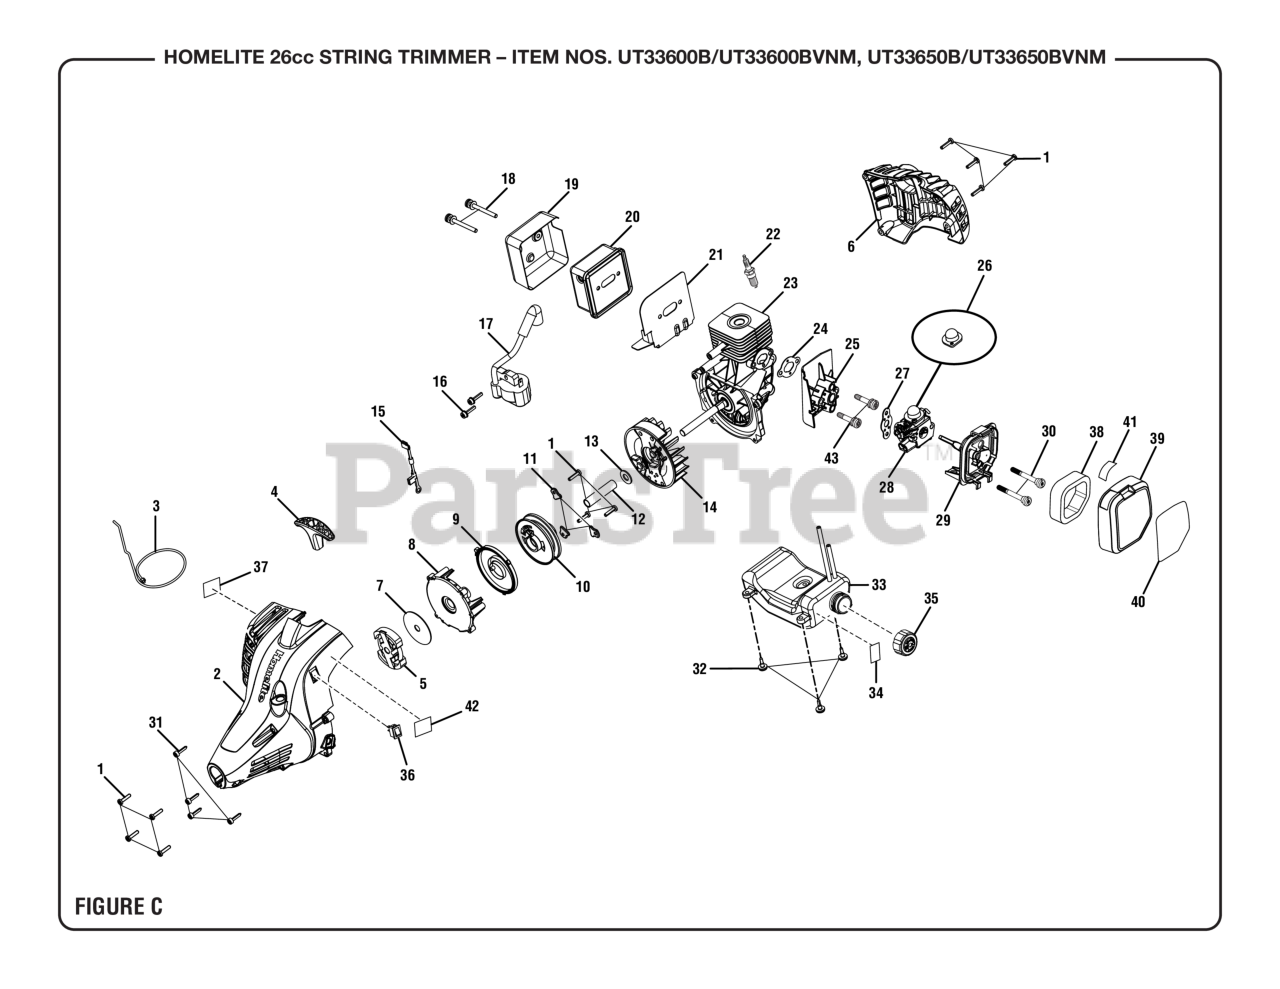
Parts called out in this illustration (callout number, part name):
1	Screw (M4 x 20 mm, T20 Torx Pan Hd. S.T.)
2	Starter Housing Assembly
3	Starter Rope (42 in.)
4	Pulley Handle
5	CLUTCH ASSEMBLY
6	Rear Housing
7	Washer (ID9.63 x OD50.75 x 1.10t)
8	Starter Housing
9	Spring & Container Assembly
10	Starter Pulley Assembly
11	Pulley Retainer
12	Spacer Tube
13	Washer (ID9.75 x OD20 x 1.6t)
14	Flywheel Assembly
15	Lead Assembly
16	Screw w/Washer (M4 x 19 mm, T20 Torx Pan Hd. S.T.)
17	Ignition Module
18	Screw w/Washers (10-24 x 2-1/8 in., T25 Torx Truss Hd.)
19	Muffler Housing
20	Muffler Assembly (Non "A" versions)
21	Muffler Gasket
22	SPARK PLUG CHAMPION - RCJ-6Y
23	Short Block Assembly
24	Inner Heat Dam Gasket
25	Heat Dam Deflector
28	Carburetor Assembly
29	Airbox Base Assembly
30	Screw (M5 x 45 mm, T20 Torx Truss Hd.)
31	Screw w/Washer (M4 x 16 mm, T25 Torx Truss Hd.)
32	Shoulder Screw w/Washer (M4 x 14 mm, T25 Torx Truss Hd.)
33	Fuel Tank w/Label & Cap Assembly
34	Fuel Tank Warning Label
35	Fuel Cap Assembly
36	Stop Switch (Momentary Contact)
37	Warning Label (Combustion)
38	Air Filter (Element)
39	Air Box Cover
40	Starting Label
41	Choke Label
42	Primer Bulb Location Label
43	Screw w/Washers (M5 x 30 mm, T25 Torx Pan Hd.)
